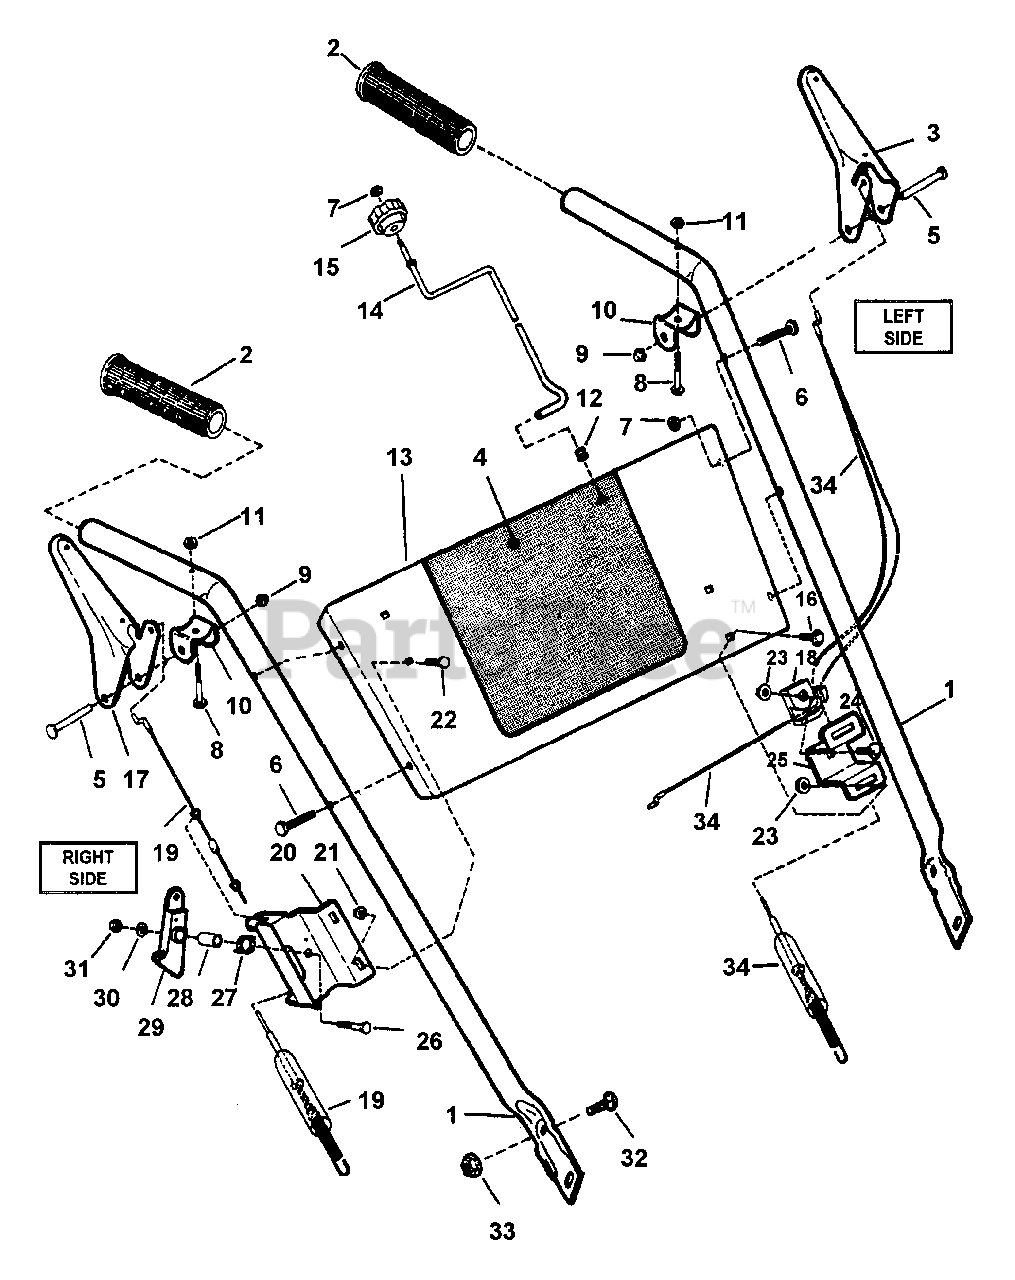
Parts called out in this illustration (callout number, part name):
1	BAR, Handle (Left Hand)
2	GRIP, Handle
3	HANDLE (Left Hand)
4	DECAL, Control Model 7/24
5	PIN, 1/4 x 1-7/8" Clevis
6	SCREW, 5/16-18 x 1-1/2" Hex Head Cap, Grade 5
7	NUT, 5/16-18 Hex Center Lock, Grade B
8	SCREW, 1/4-28 x 1-3/8" Hex Head Cap, Grade 5
9	NUT, 1/4" Push
10	BRACKET, Handle
11	NUT, 1/4-28 Hex Top Lock
12	BUSHING
13	PANEL, Control
14	CRANK, Chute
15	KNOB, Chute Crank
16	BOLT, 1/4-20 x 1/2" Short Neck Carriage, Grade 5
17	HANDLE (Right Side)
18	GUIDE, Cable
19	CABLE, Auger Right Side
20	CAM BRACKET
21	NUT, #10-24 Hex Flange Lock
22	BOLT, #10-24 x 1/2" Flat Head Carriage
23	NUT, 1/4-20 Hex Flange Lock
24	BOLT, 1/4-20 x 3/4" Short Neck Carriage, Grade 5
25	BRACKET, Cable Guide Support
26	SCREW, 1/4-20 x 1" Hex Head Cap, Grade 5
27	SPRING, Cam Lock
28	SPACER
29	CAM LOCK
30	WASHER, 1/4" Flat
31	NUT, 1/4-20 Hex Center Lock, Grade B or 5
32	BOLT, 5/16-18 x 5/8" Short Neck Carriage, Grade 5
33	NUT, 5/16-18 Hex Flange Lock, Grade 5
34	CABLE, Clutch (Left Hand)
